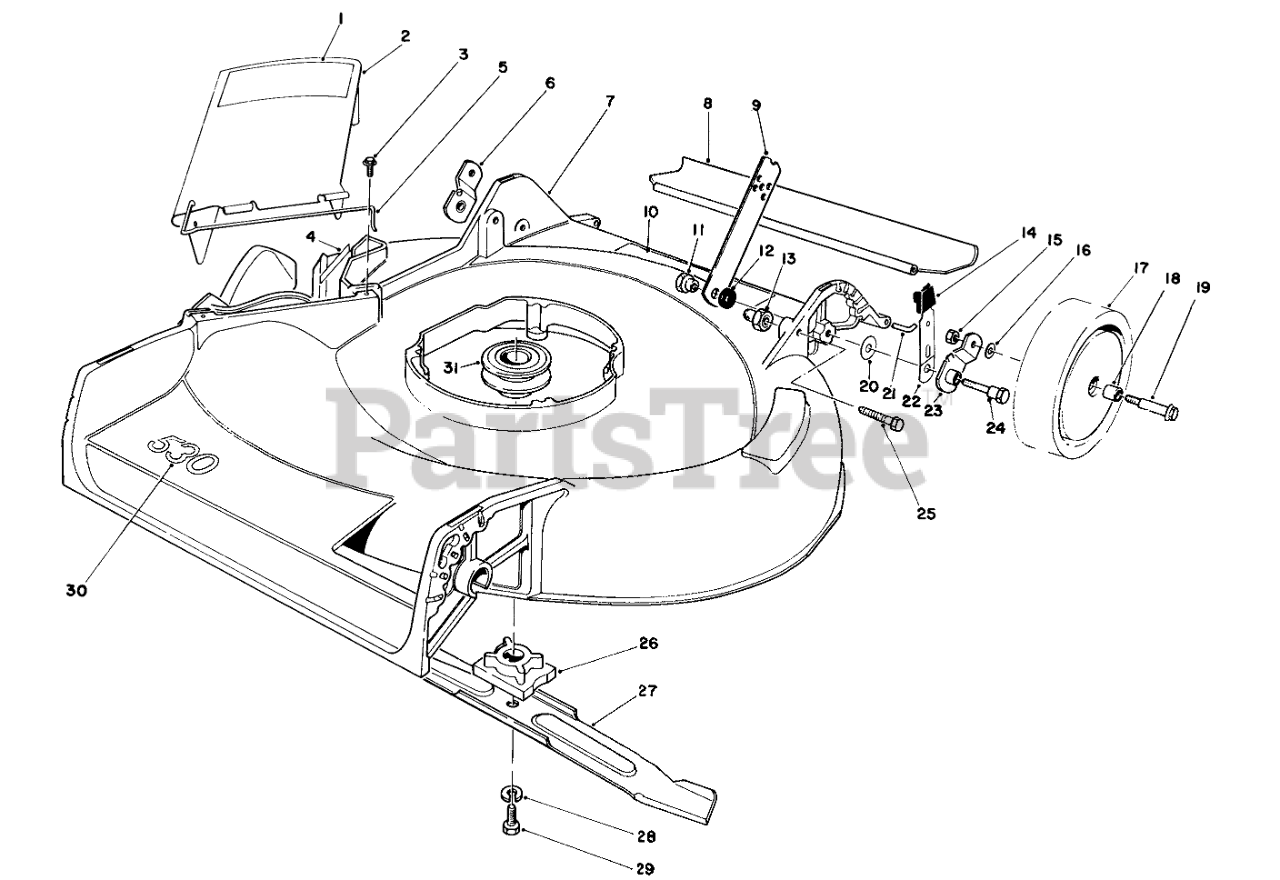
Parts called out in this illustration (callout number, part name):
1	DANGER DECAL
2	Deflector Assembly (Incl.Ref. #1 & 5)
3	SCREW-HWH
4	Decal-Danger
5	SPRING HINGE
6	Pivot Arm
7	Housing
8	REAR SAFETY SHIELD 21
9	HANDLE LATCH
10	DECAL-DANGER
11	HANDLE PIVOT NUT
12	SPACER
13	HANDLE PIVOT NUT
14	KNOB-ARM
15	NUT-LOCK
16	WASHER
17	Wheel & Tire Assembly (Incl. Ref. #18)
18	BUSHING
19	WHEEL BOLT
20	WASHER-PIVOT
21	SHIELD ROD
22	SPRING ARM ASM
23	Pivot Arm
24	PIVOT SCREW
25	SCREW-HH
26	BLADE RETAINER
27	Blade
28	WASHER-LOCK
29	SCREW-HH
30	Decal-530
31	PULLEY-DRIVER
